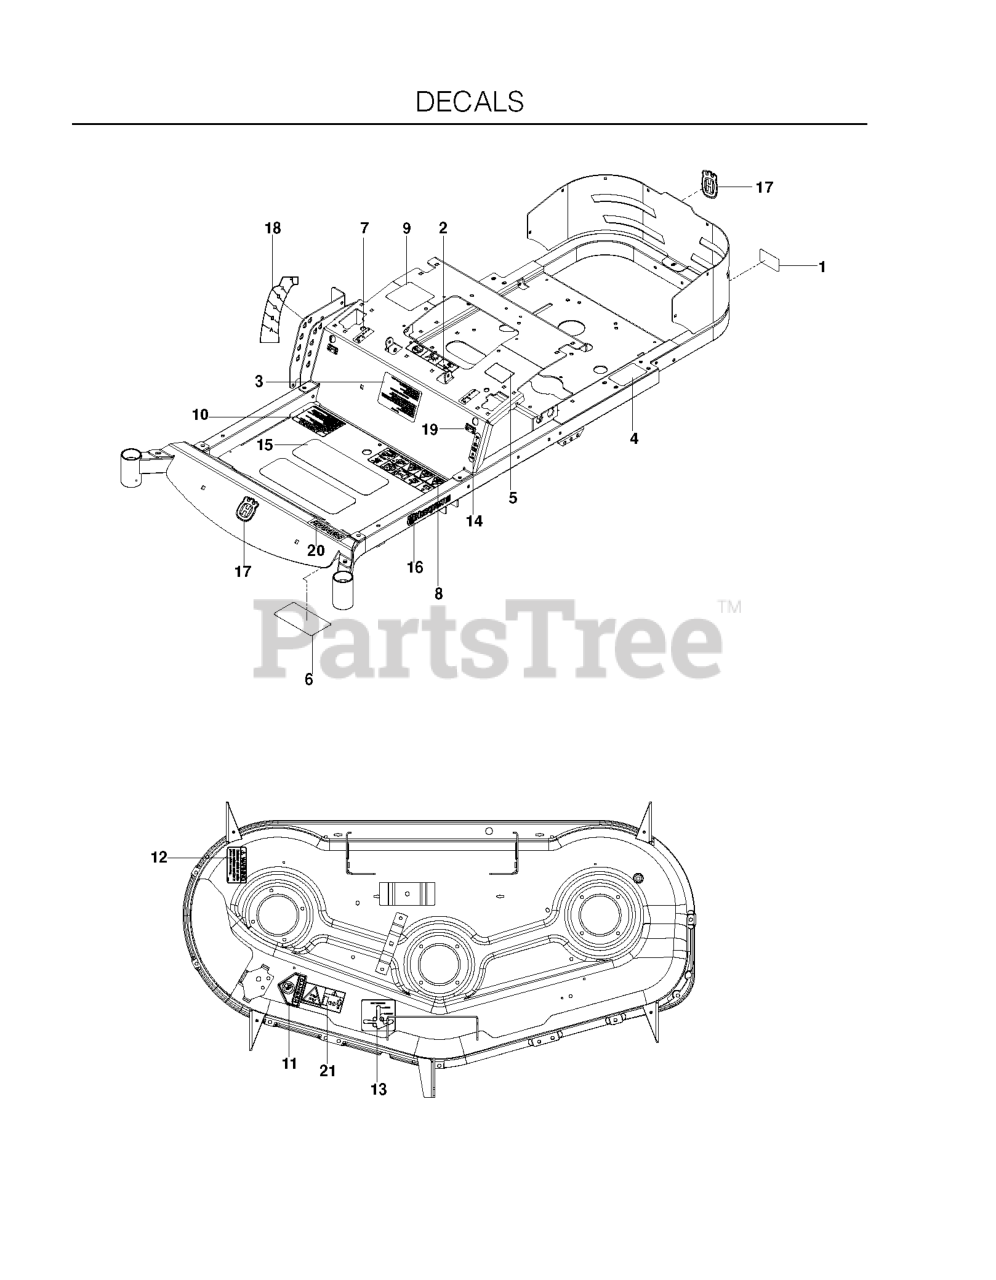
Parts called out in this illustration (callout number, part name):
1	DECAL, PROP. 65
2	EURO DECAL-BATTERY WARNIN6
3	DECAL, START
4	DECAL, DO NOT TOW
5	DECAL, EXITING MOWER
6	DECAL, SERVICE
7	DECAL, MOTION CONTROL
8	DECAL, SAFETY WARNING
9	DECAL, CUSTOMER RESPNSIBILITY
10	DECAL, WARNING
11	DECAL, CPSC
12	DECAL, CAUTION
13	DECAL, BELT ROUTING
14	DECAL, PARK BRAKE
15	ANTI-SKID PAD
16	DECAL.HOOD.LOGO.ORANGE.HUSQVAR
17	DECAL, CROWN H 70MM
18	DECAL, HEIGHT
19	DECAL, F.S.T.
20	DECAL, EZ4824
21	DECAL, EURO SEVERING
